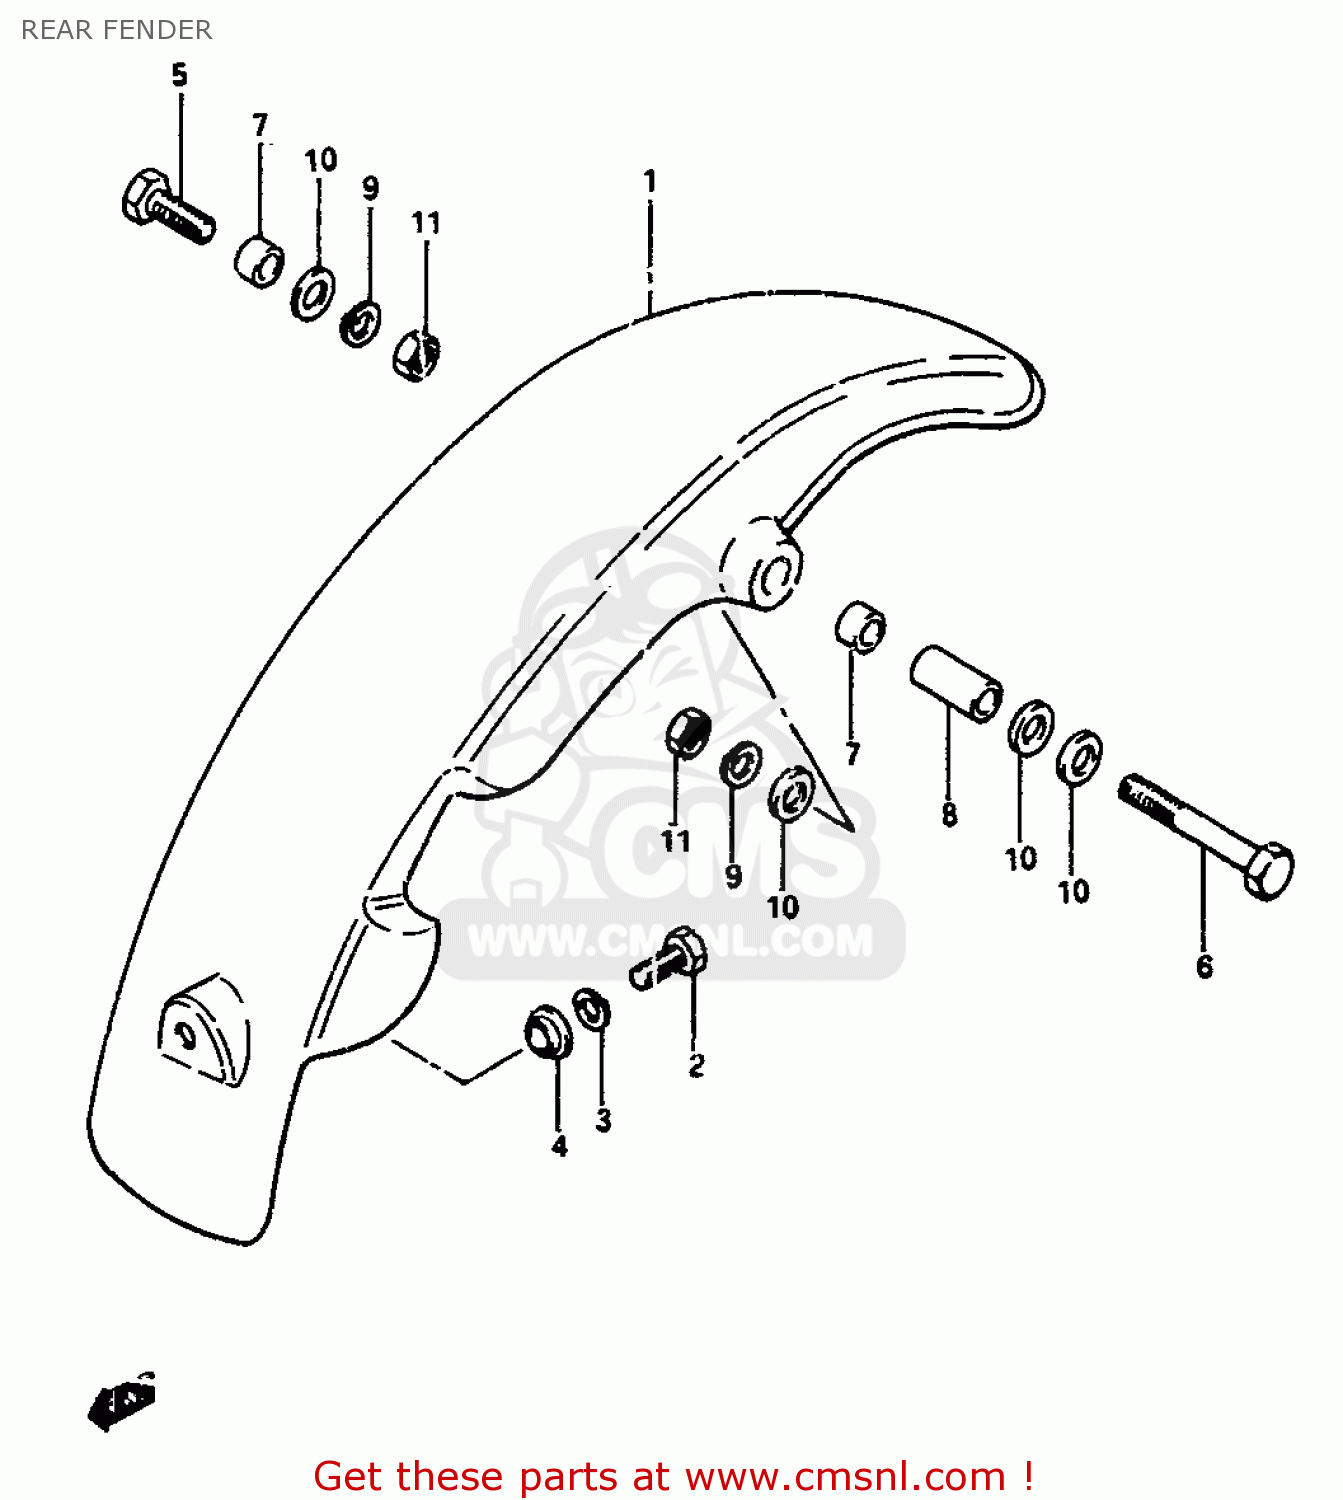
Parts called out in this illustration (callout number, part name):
1	FENDER,RR
2	BOLT
3	WASHER,LOCK
4	WASHER
5	BOLT
6	BOLT 8X50
7	SPACER,RR FENDER RR
8	SPACER (8.2X12.5X23.5)
9	LOCK WASHER
10	WASHER
11	NUT
